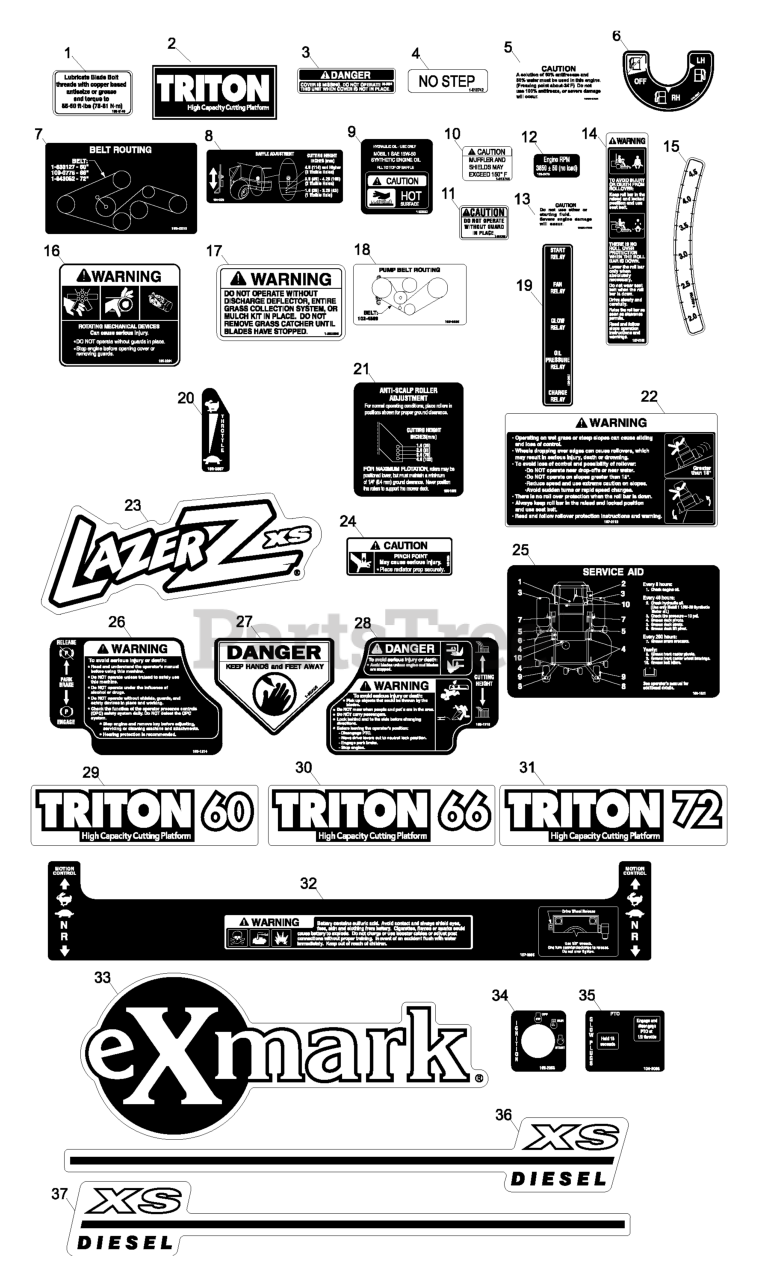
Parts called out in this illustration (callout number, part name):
1	DECAL,BOLT TORQUE
3	DECAL-COVER, MISSING
4	DECAL,NO STEP
5	DECAL-ANTIFREEZE
6	DECAL-VALVE, FUEL
7	DECAL,BELT ROUTING
8	DECAL,BAFFLE ADJUSTMENT
11	DECAL-GUARD
13	DECAL-CAUTION
14	DECAL-WARNING, FOLDING RO
15	DECAL-HEIGHT, DECK
16	DECAL,WARNING
17	DECAL-WARNING, DISCHARGE
18	DECAL,PUMP BELT ROUTING
19	DECAL,RELAY KUBOTA
20	DECAL, THROTTLE
21	DECAL,ANTISCALP
22	DECAL-WARNING
23	DECAL,LAZER XS MODEL
24	DECAL,RADIATOR ASSEMBLY
25	DECAL,SERVICE AID
26	DECAL,PARK BRAKE
27	DECAL-DANGER
28	DECAL,DECK HEIGHT
29	DECAL,TRITON 60
30	DECAL,TRITON 66
31	DECAL,TRITON 72
32	DECAL-CONSOLE, TOP
33	DECAL,EXMARK
34	DECAL,IGNITION
35	DECAL, PTO/GLOW PLUG
36	DECAL,HOOD LXS DIESEL RH
37	Decal, Hood Lh
